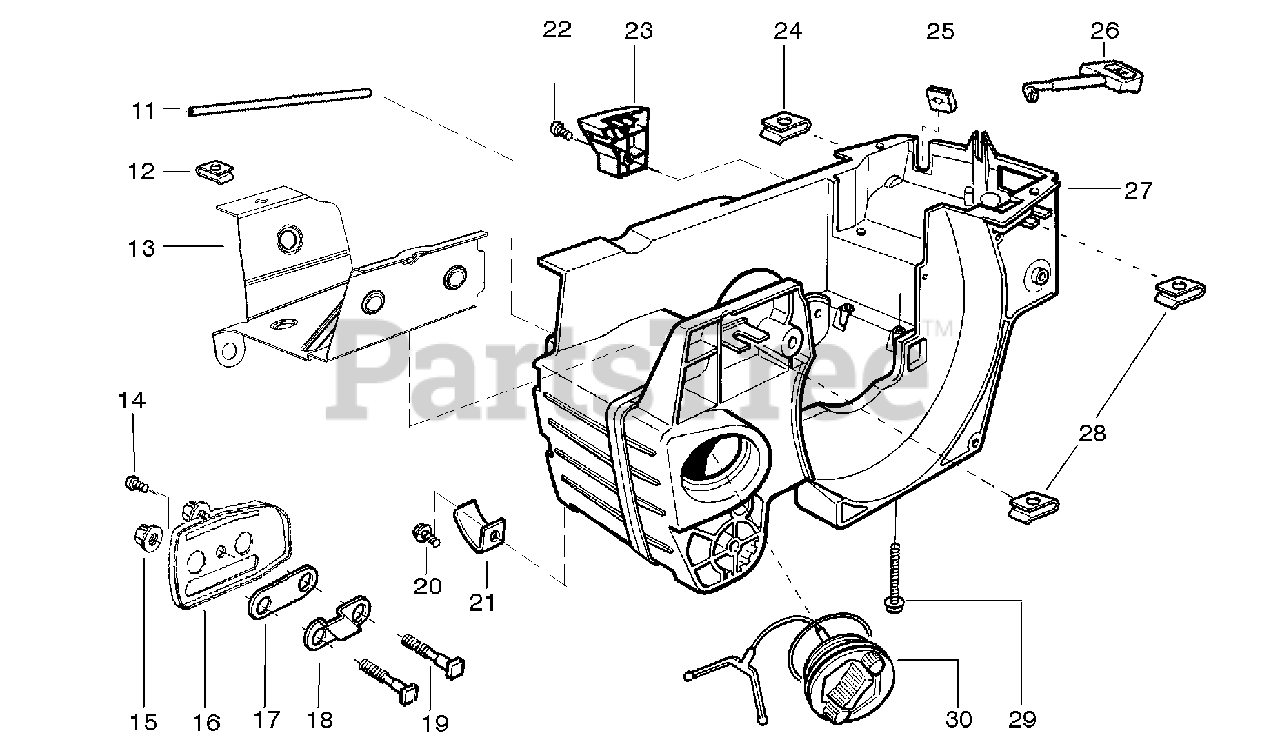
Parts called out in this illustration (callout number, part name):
11	Tube-Oil Vent
12	Clip-Retainer
13	Shield-Heat
14	Screw
18	Plate-Bar Stud
21	Chain Catcher
24	Nut-Type "U" Speed
26	Lever-Choke
27	Kit - Chassis Ass’y.
28	Nut-Type "U" Speed
30	Assy.- Oil Tank Cap
